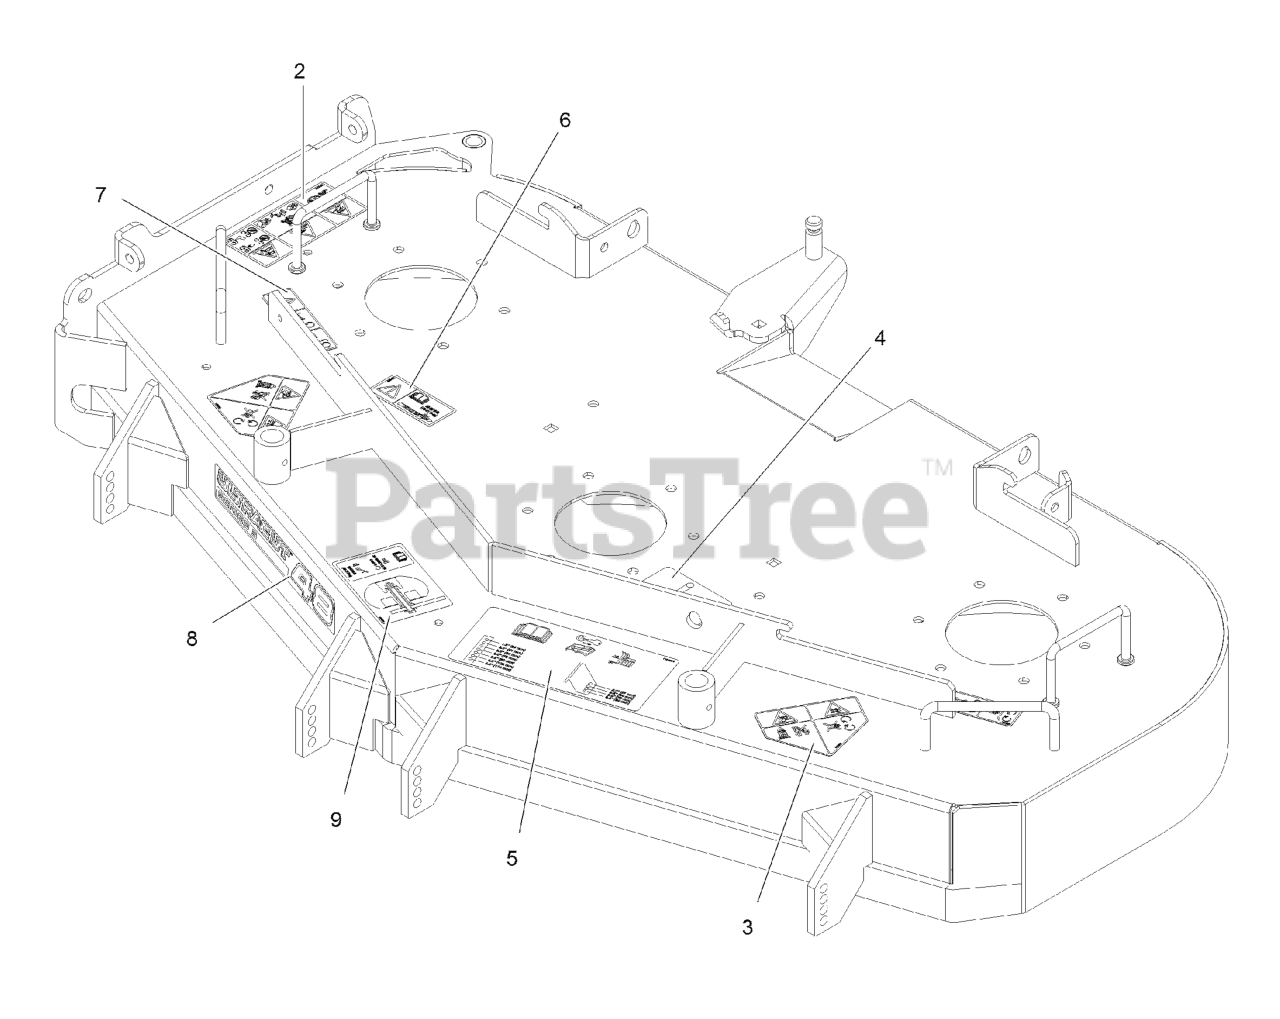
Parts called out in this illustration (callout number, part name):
2	DECAL-WARNING THROWN OBJ
3	DECAL-DANGER
4	DECAL-BELT ROUTING
5	DECAL-ANTI-SCALP
6	DECAL-BOLT TORQUE
7	DECAL-COVER, MISSING
8	DECAL-ULTRACUT 48 SERIES
9	DECAL-ROLLER MOUNTING
